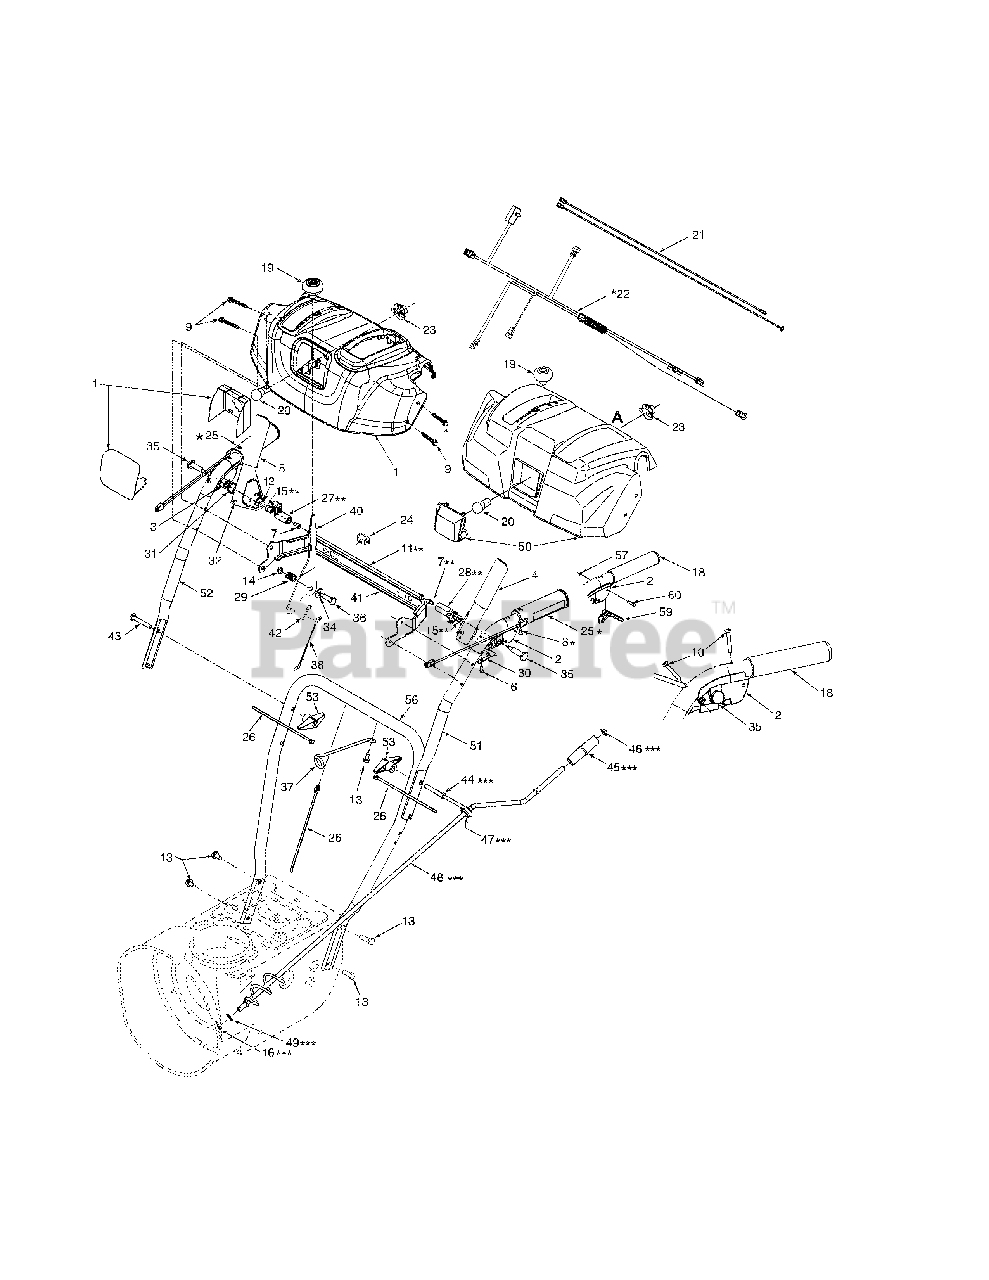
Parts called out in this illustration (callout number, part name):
1	Handle Panel Ass’y - Yellow
1	Handle Panel Ass’y - Black
1	Handle Panel Ass’y-Black w/Chute Control
2	LH Clutch Lock Handle Ass’y
3	RH Clutch Lock Handle Ass’y
4	Engagement Handle Assembly LH
5	Engagement Handle Assembly RH
6	Screw #8-16 x .50
7	Hex Cap Socket Screw 1/4-20 x .5
8	Oval HD C-Sunk Scr #10 x 5/8
9	Hex TT-Tap Scr 1/4-20 x 1.625
10	Oval C-Sunk Hd Screw 10-24 x 1.375
13	Hex TT Screw 3/8-16 x .75
14	Hex L-Flanged Nut 1/4-20 Gr. F Nylon
15	Hex Shoulder Nut 1/4-20
15	Hex L-Flg Nut 1/4-20 Gr. F Nylon
16	Int. Cotter Pin .072 x 1.13" Lg.
19	Shift Knob - Yellow
20	Lamp #1295
21	Wire Harness (w/sq. alternator connector)
22	Heated Grip Wire Harness
23	Socket
26	Cable Tie (w/plug)
26	Cable Tie (w/heated grips)
27	Lock Plate
28	Clutch Lock Cam
29	Compression Spring .38 ID x .88 Lg
30	Spring: Clutch Lock
31	Torsion Spring .8156 x .3038
32	Rubber Bumper
34	Flat Washer .38 ID x .87 OD x .09
35	Shoulder Screw .437 x 1.345: 1/4-20
36	Shoulder Screw .374 Dia. x 1.05 Lg.
37	Cable Guide (W/B&S engine)
38	Selector Speed Cable
43	Carriage Bolt 5/16-18 x 2.25
44	Chute Crank Eye Bolt Special
45	Knob 1.0 x 3.2
46	Push Nut 3/8" Rod
47	Grommet
49	Flat Washer .406" I.D. x .75" O.D.
50	Handle Panel Ass’y - Troy-Bilt
53	Handle Knob Assembly
59	Steering Control
